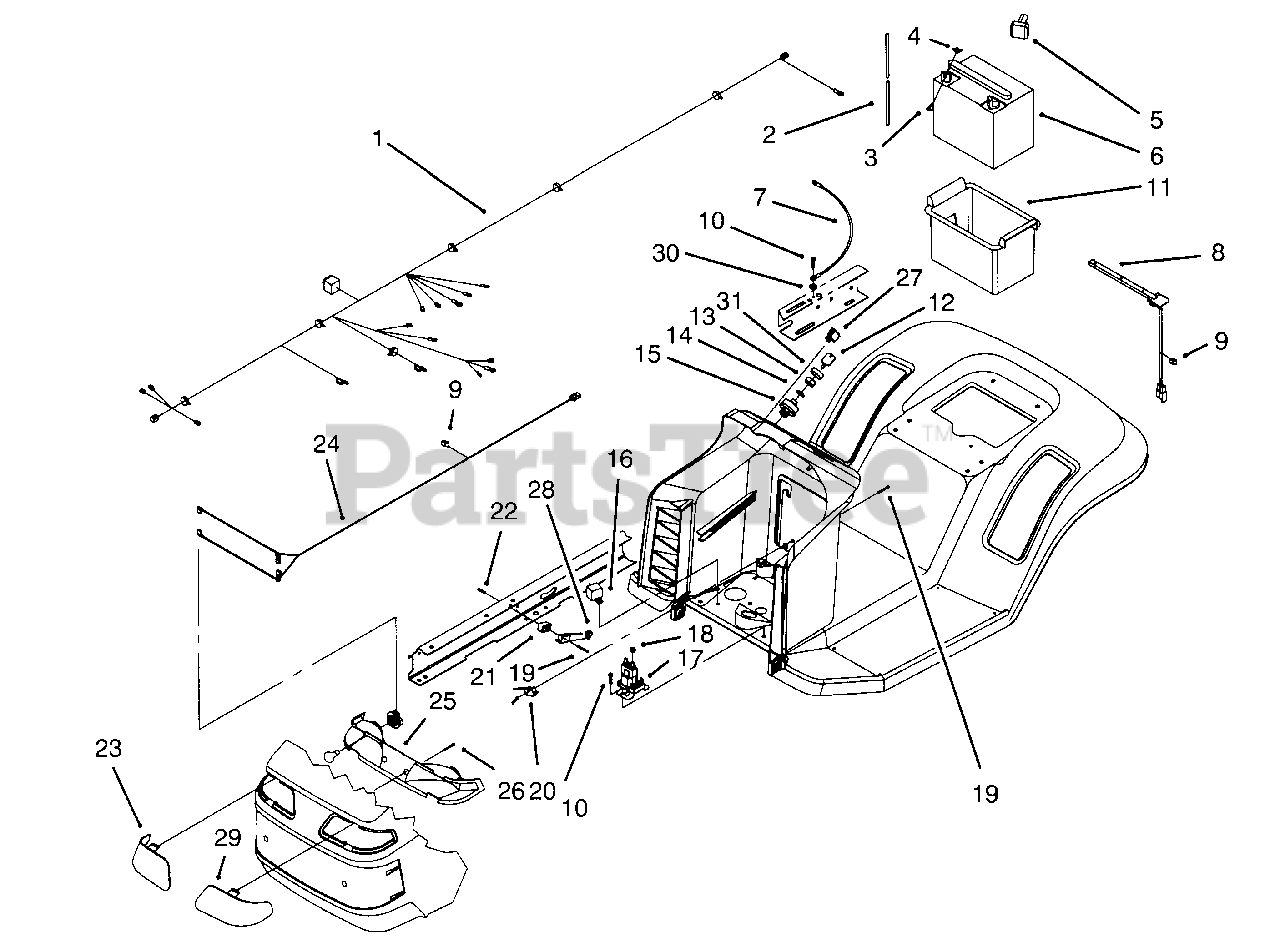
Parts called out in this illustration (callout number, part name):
1	Harness-Wire
2	Vent-Tube
3	Screw-Hex Hd. Cap
5	Boot-Battery Terminal
6	Battery-7 Plate
7	Cable-Battery Negative
8	Switch-Seat
9	Clip-Wire Retainer
10	Screw-Hex Hd. Thr'd Forming
11	Box-Battery
12	Key-Ignition
14	Washer-Lock
15	Switch-Ignition(Incl Ref. #13, 14)
17	Solenoid
18	Nut-Keps
19	Screw-Phillips Hd.
20	Switch-Micro
21	Spacer-Microswitch
23	Lens-R.H.
24	Harness-Wire
25	Reflector & Lamp
26	Screw-Plastite
27	Switch-Rocker
28	Seal-Plunger
29	Lens-L.H.
30	Washer-Lock
